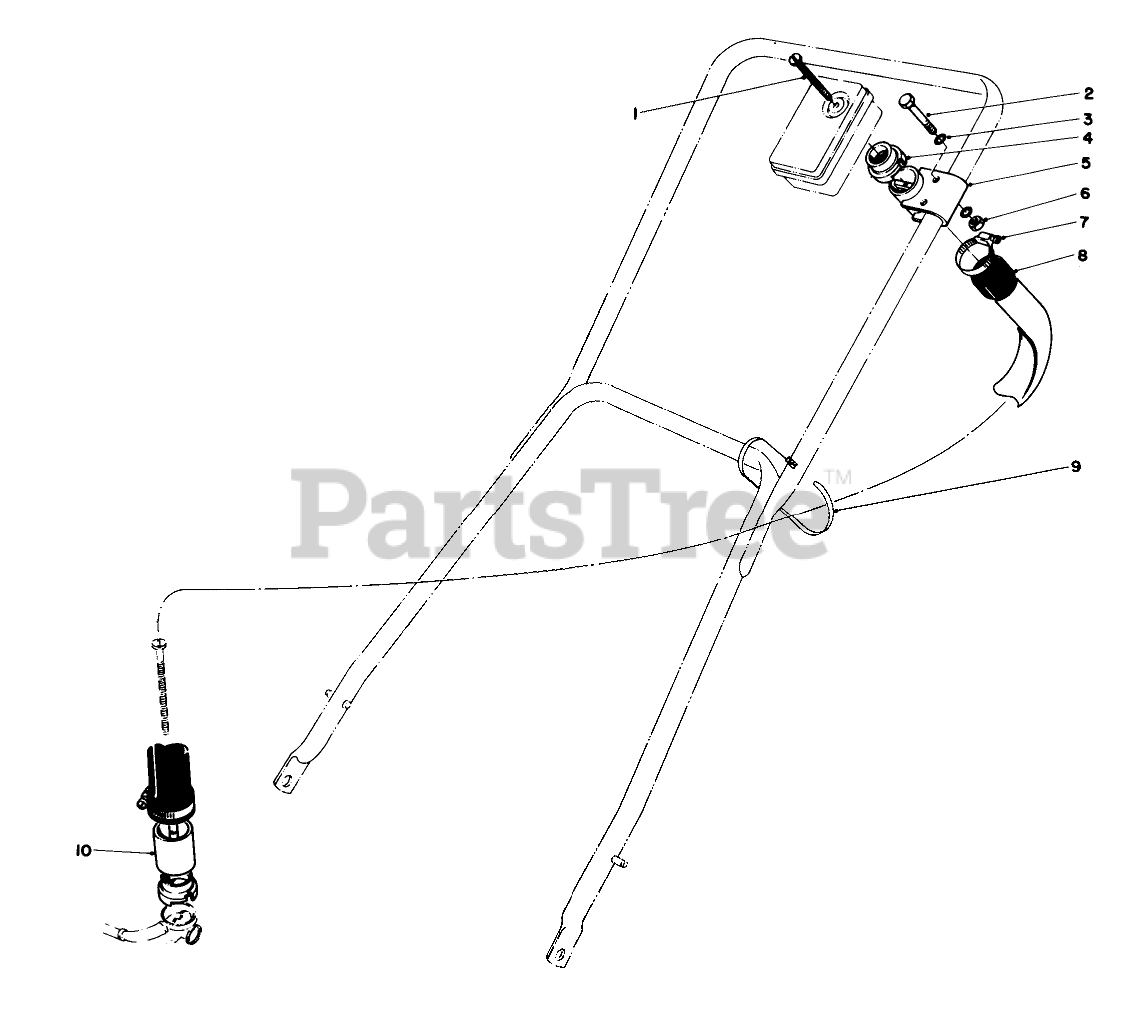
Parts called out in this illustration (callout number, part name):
1	Pan Hd. Machine Screw
2	SCREW-HH
3	WASHER-PLAIN
4	GASKET
5	Mounting Bracket Air Cleaner
6	NUT-HEX
7	CLAMP-HOSE
8	Hose Air Cleaner
9	TIE-CABLE
10	HOSE COUPLING WA B
